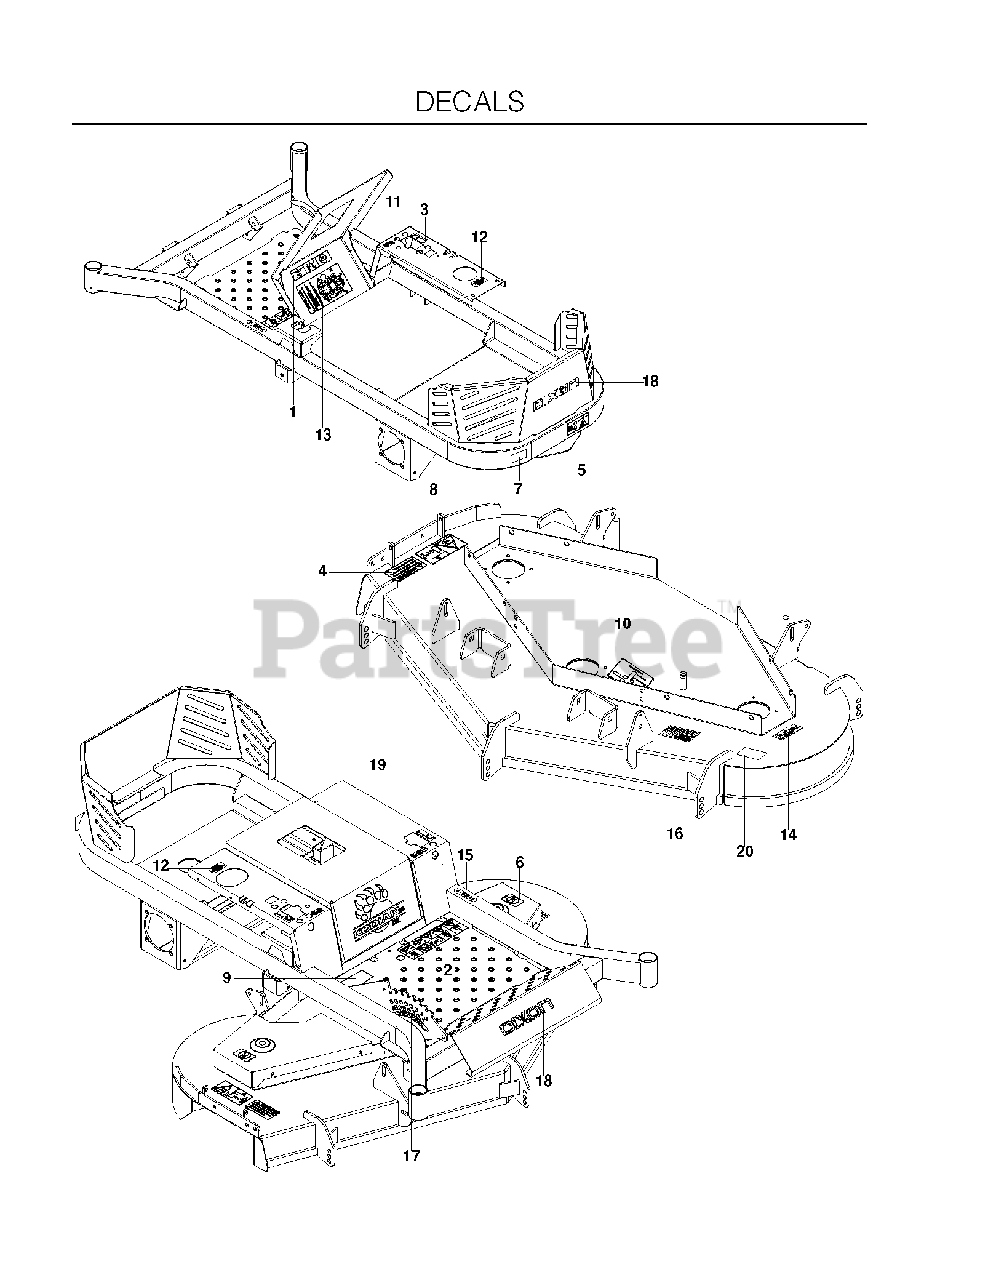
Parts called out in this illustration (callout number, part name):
1	DECAL, BATTERY
2	DECAL, WARNING
3	DECAL, MOTION CONTROL
4	DECAL, DISCHARGE, MULTILINGUAL
5	DECAL, BELT DRIVE
6	DECAL, NO STEP
8	DECAL, EURO SEVERING
10	DECAL, BELT ROUTING
11	DECAL, F.S.T.
12	DECAL, OIL TANK
13	DECAL, SERVICE
14	DECAL, FUSION
15	DECAL, PARK BRAKE
16	DECAL, TRI-FORCE COMM
17	DECAL, HEIGHT 5"
18	DECAL, DIXON LOGO, DOMED
19	DECAL, KODIAK SE
20	DECAL, 52"
